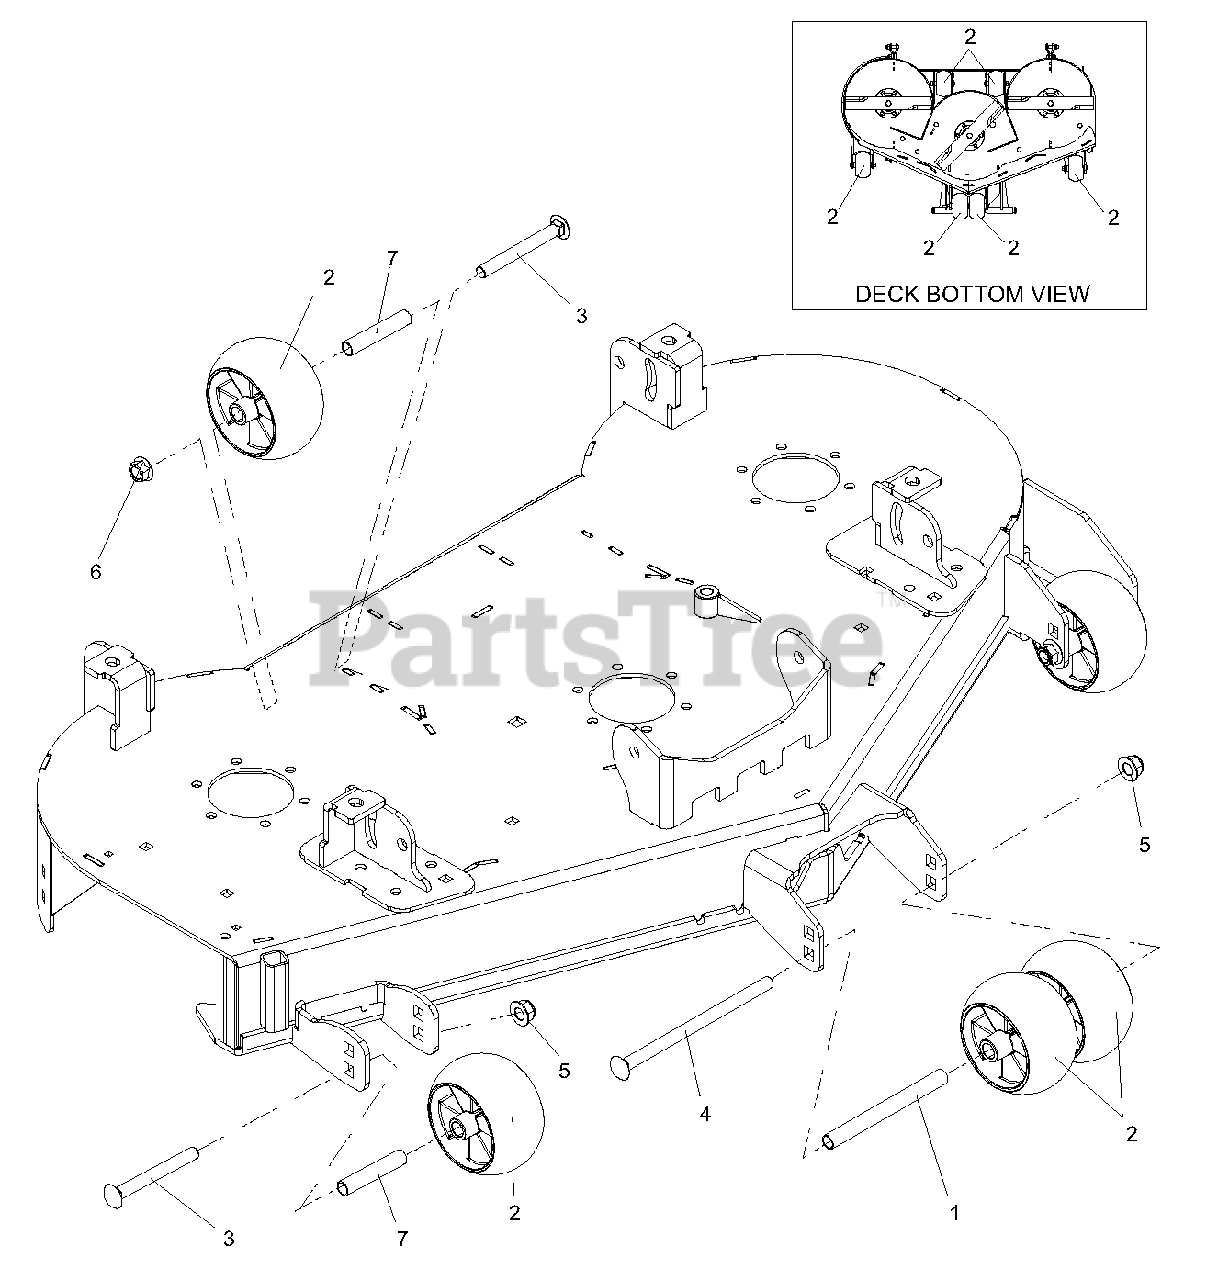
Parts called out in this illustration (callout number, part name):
1	SPACER, .510 X .625 X .6.70
2	ANTI-SCALP WHEEL 5X3 CTR
3	BLT-HEX .50-13 X 4.50 G5 YWZC
4	BLT-RDHDSQNK .50-13 X 8.50
5	NUT-LK-NYL-FLG .50-13 YWZC
6	NUT .50-13 WIZ FLANGE
7	SPACER, .510 X .625 X 3.25
